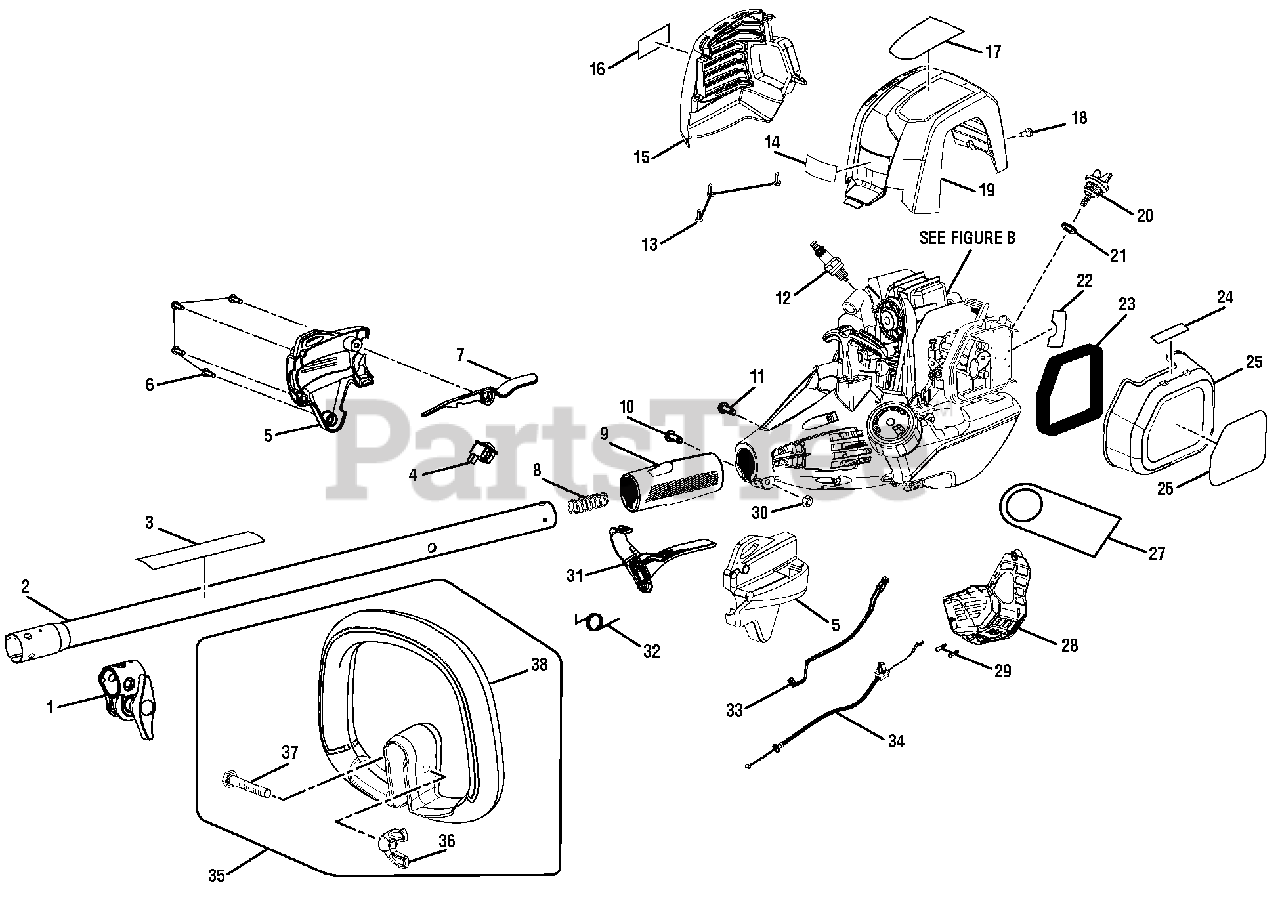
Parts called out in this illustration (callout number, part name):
1	Boom Clamp Assembly
2	Upper Boom Assembly
3	Warning Label
4	Switch (Momentary Contact)
5	Control Handle Assembly
6	Screw (M4 x 20 mm, T20 Torx Pan Hd.)
7	Trigger Lock
8	Compression Spring
9	Rear Handle
10	Bolt (M6 x 20 mm, T27 Torx Button Hd.)
11	Screw (M4 x 8 mm, T25 Torx Pan Hd. T.F.)
12	Spark Plug (Champion RY4C)
13	Screw (M4 x 12 mm, T20 Truss Hd.)
14	Logo Label
15	Muffler Housing
16	Combustion Warning Label
17	X430 Label
18	Shoulder Screw (M4 x 11 mm, T25 Torx Pan Hd.)
19	Top Cover
20	Oil Cap/Dipstick
22	Hot Surface Label
23	Air Filter
24	Choke Label
25	Air Filter Cover
26	Starting Label
27	Oil Hang Tag
28	Bottom Cover
29	Screw (#6-19 x 1/2 in., Phillips Hd. T.F.)
30	Hex Nut (M6)
31	Throttle Trigger
32	Torsion Spring (Throttle Trigger)
33	Lead Assembly
34	Throttle Cable
35	Front Handle Assembly
36	Wing Nut (1/4-20)
37	Screw (1/4-20 x 40 mm, Hex Hd.)
38	Front Handle
